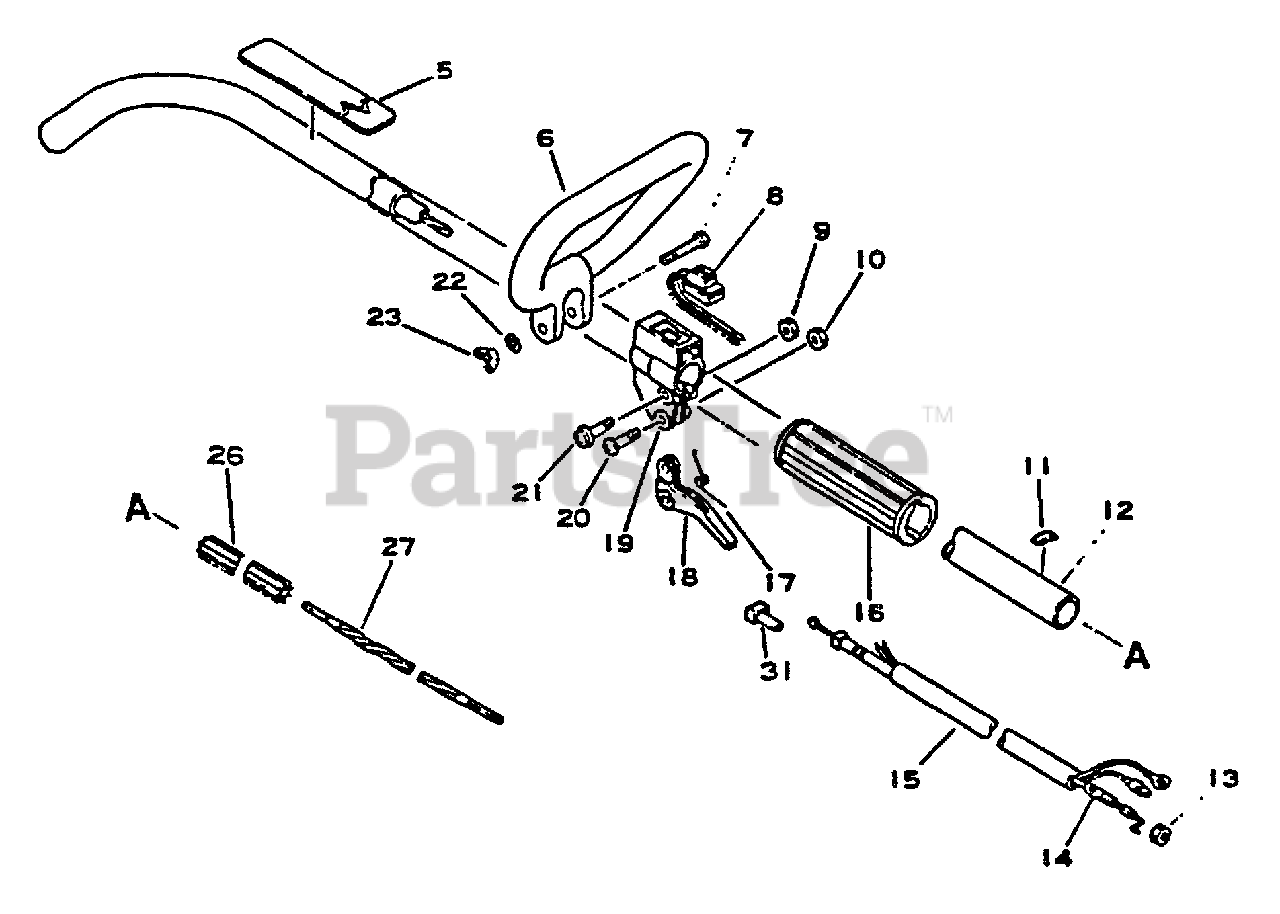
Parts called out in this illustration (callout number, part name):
5	LABEL - CAUTION
6	HANDLE
7	BOLT - 6X40
8	IGNITION SWITCH ASSY
10	LOCKNUT - 5
11	LABEL - ALIGNMENT
12	MAIN PIPE ASSY
14	CABLE, THROTTLE
15	TUBE - VINYL
16	GRIP, HANDLE
17	SPRING, TRIGGER
18	TRIGGER, THROTTLE
19	BRACKET, THROTTLE CONTROL
20	SCREW - 5X30
21	SCREW - 5X28
22	WASHER - 6
23	WINGNUT - 6
26	LINER - FLEXIBLE
27	DRIVESHAFT - FLEXIBLE
31	GUIDE, CABLE
